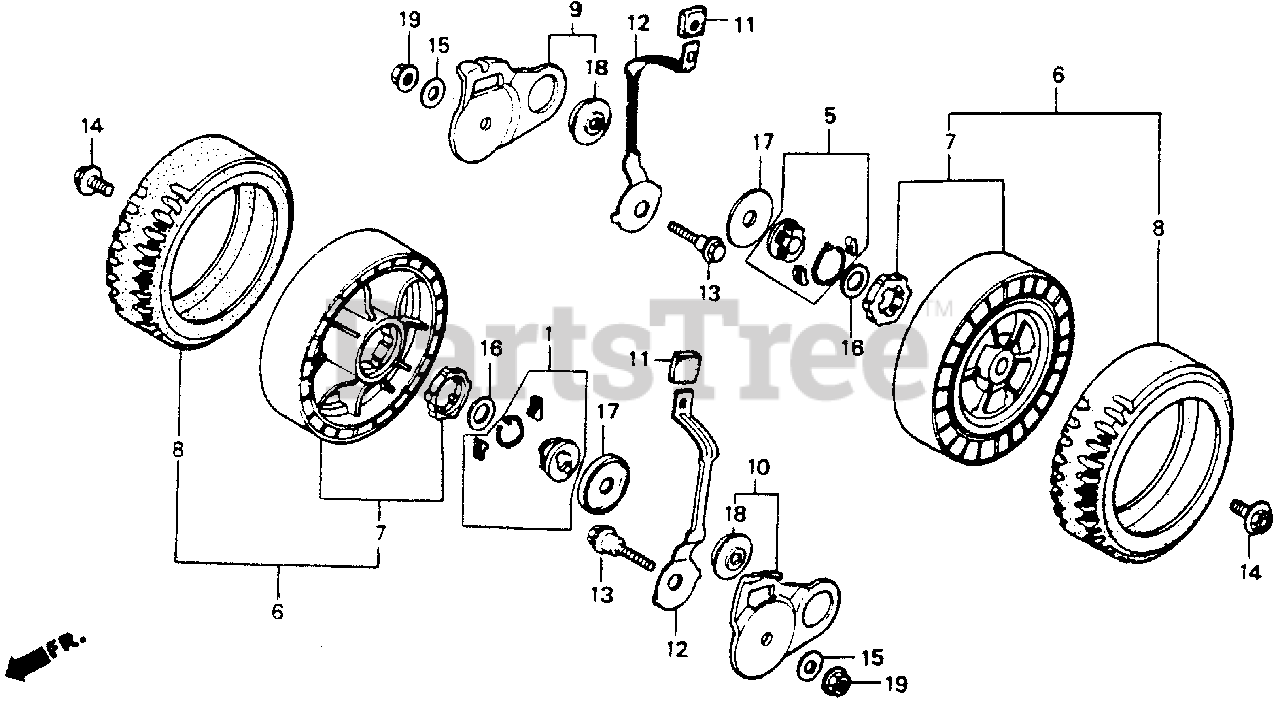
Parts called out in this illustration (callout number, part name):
1	HOLDER, R. RATCHET
5	HOLDER, L. RATCHET
7	HUB, WHEEL (NA USE ALT:42810-VA3-J00)
8	TIRE (8 INCH)
9	ARM C, L. WHEEL ADJUSTER
10	ARM D, R. WHEEL ADJUSTER
11	GRIP, ADJUSTER
12	PLATE, RR. ADJUSTER
13	BOLT, ADJUSTING CENTER
14	BOLT, WHEEL
15	WASHER (8MM)
15	WASHER A, HANDLE HOLDER SETTING
16	WASHER (16MM)
17	WASHER, WHEEL
18	BEARING, RADIAL BALL
19	NUT, FLANGE (8MM)
